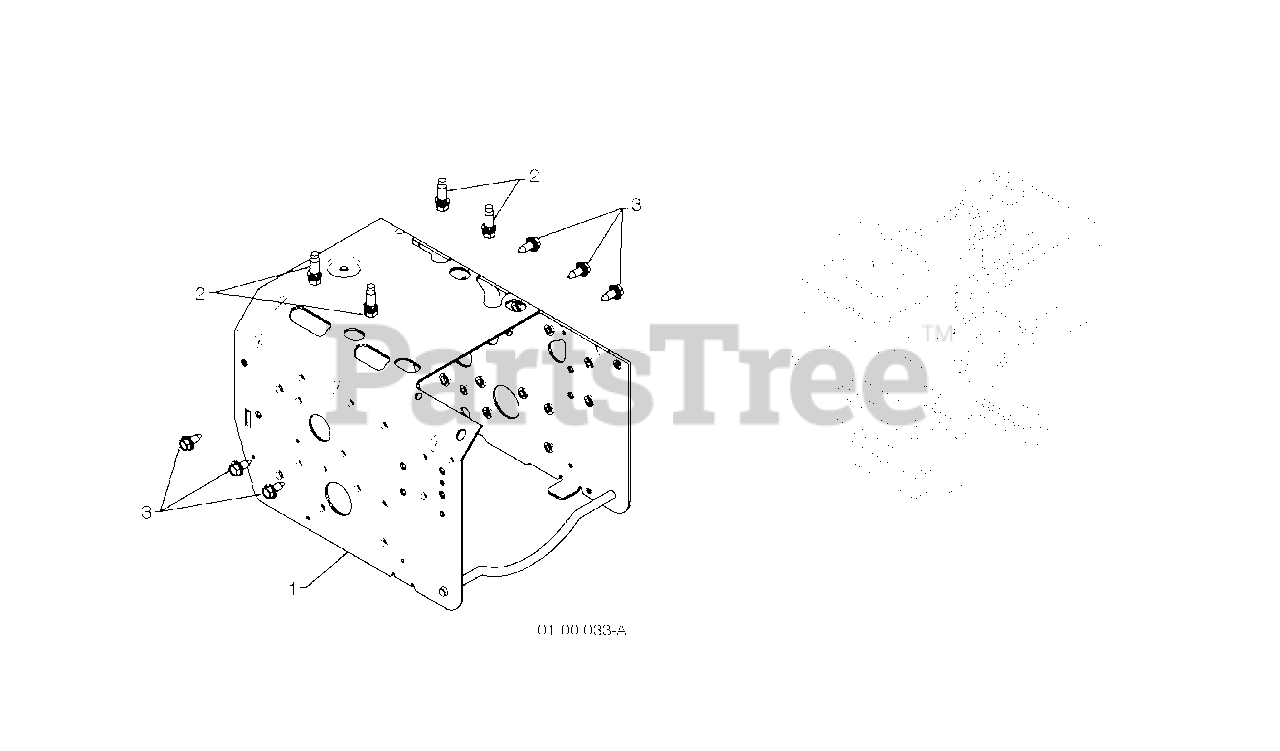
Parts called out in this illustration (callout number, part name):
1	FRAME.WELD.PNT.GEAR
2	BOLT 3/8-16X1-1/8
3	BOLT.HEX.HD.WASHER.5/16-18X.75
